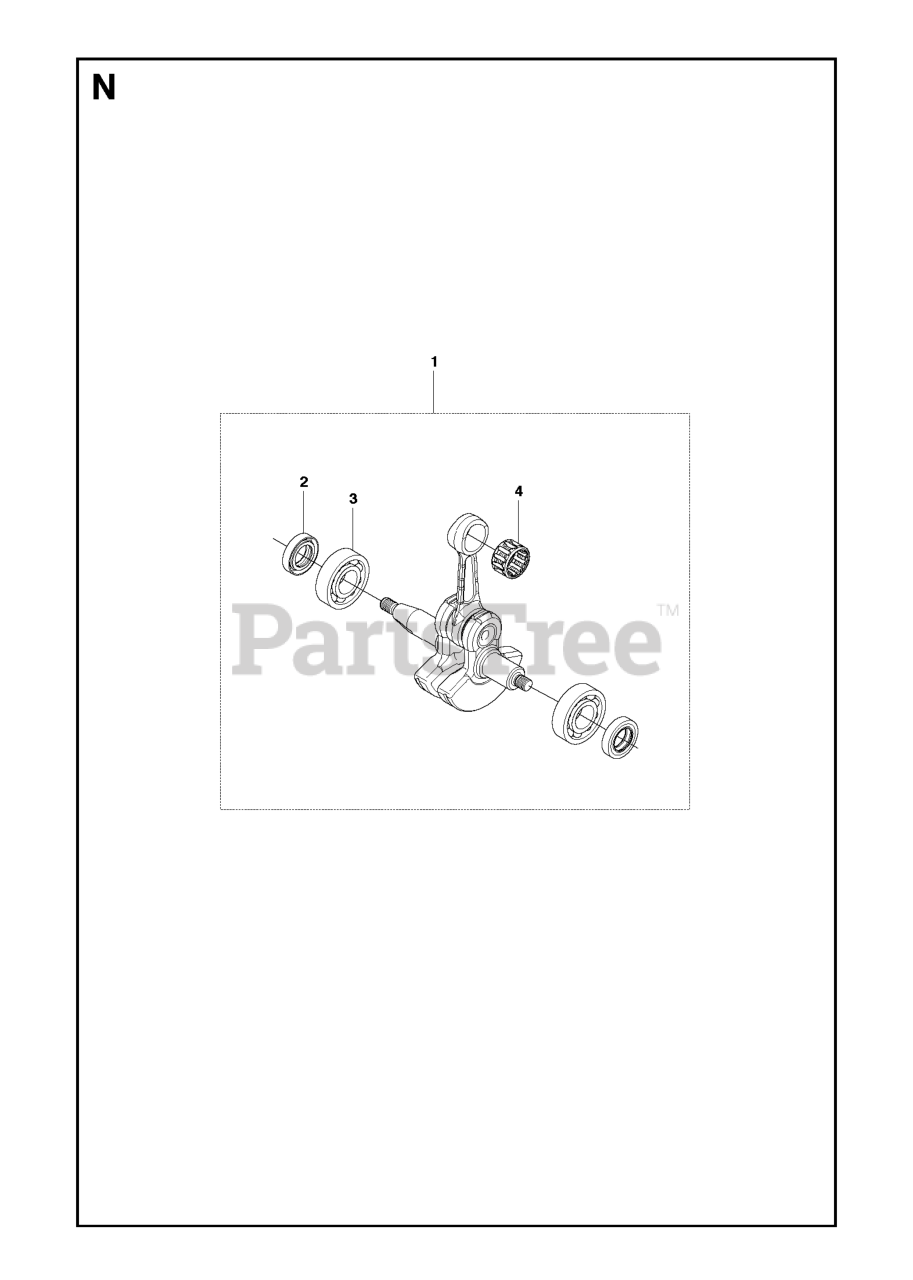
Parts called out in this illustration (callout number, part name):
1	CRANKCASE ASSY SPARE
3	SEALING RING
4	BALL BEARING
